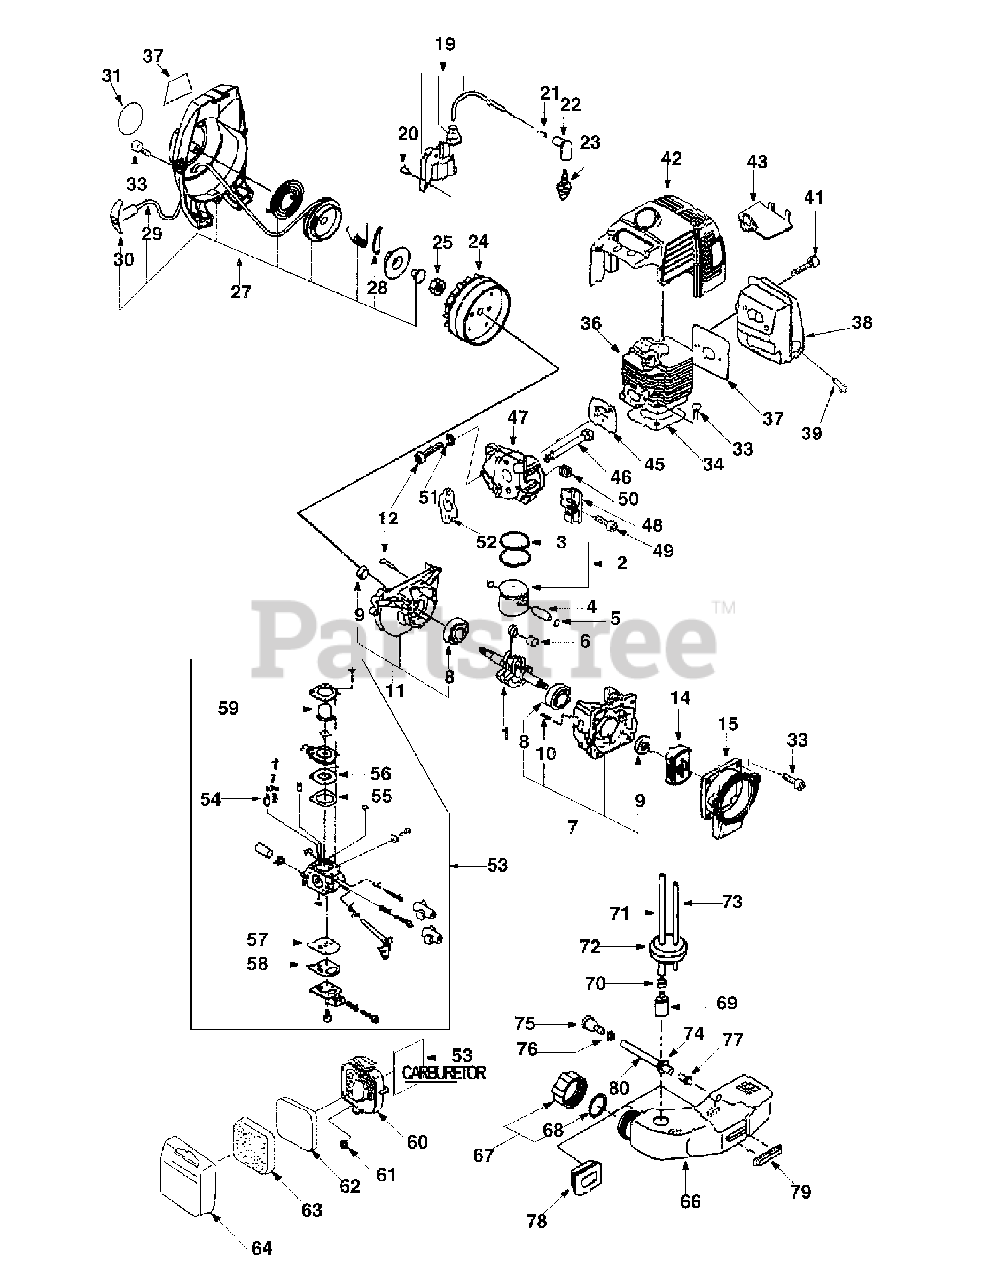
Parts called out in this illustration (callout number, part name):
1	Crankshaft
2	Piston Assembly
3	Ring, Piston
4	Pin, Piston
5	Clip, Piston Pin
6	Needle Bearing
7	Crankcase Assembly
8	Ball Bearing
9	Oil Seal
10	Dowel Pin
11	Crankcase Assembly
12	Bolt; M5 x 25
14	Clutch Assembly
19	Coil Assembly, Ignition
20	Bolt; M4 x 20
22	Cap, Plug
23	Spark, Plug
24	Flywheel, Magneto
27	Housing Assembly, Blower
29	Rope, Starter
30	Knob, Starter
31	Name Plate
32	Caution Plate
33	Bolt; M5 x 16
36	Cylinder
37	Gasket, Muffler
39	Arrester
41	Bolt; M5 x 48
42	Cowling, Cylinder
43	Baffle Plate
45	Gasket, Insulator
46	Bolt; M5 x 56
47	Insulator
48	Adjuster
49	Bolt; M5 x 12
51	Washer
52	Gasket, Carburetor
53	Carburetor Assembly
54	Valve, Float
56	Diaphragm, Metering
57	Diaphragm, Pump
60	Case, Air Silencer
62	Element (B), Air Filter
63	Element (A), Air Filter
64	Case, Cap
65	Wire Compl, Throttle
66	Tank, Fuel
67	Cap Assembly, Fuel Tank
69	Filter, Fuel
71	Hose
73	Hose
75	Valve Assembly, Reversing
77	Connector
79	Rubber
81	Gasket Kit
83	Spring, Spiral
